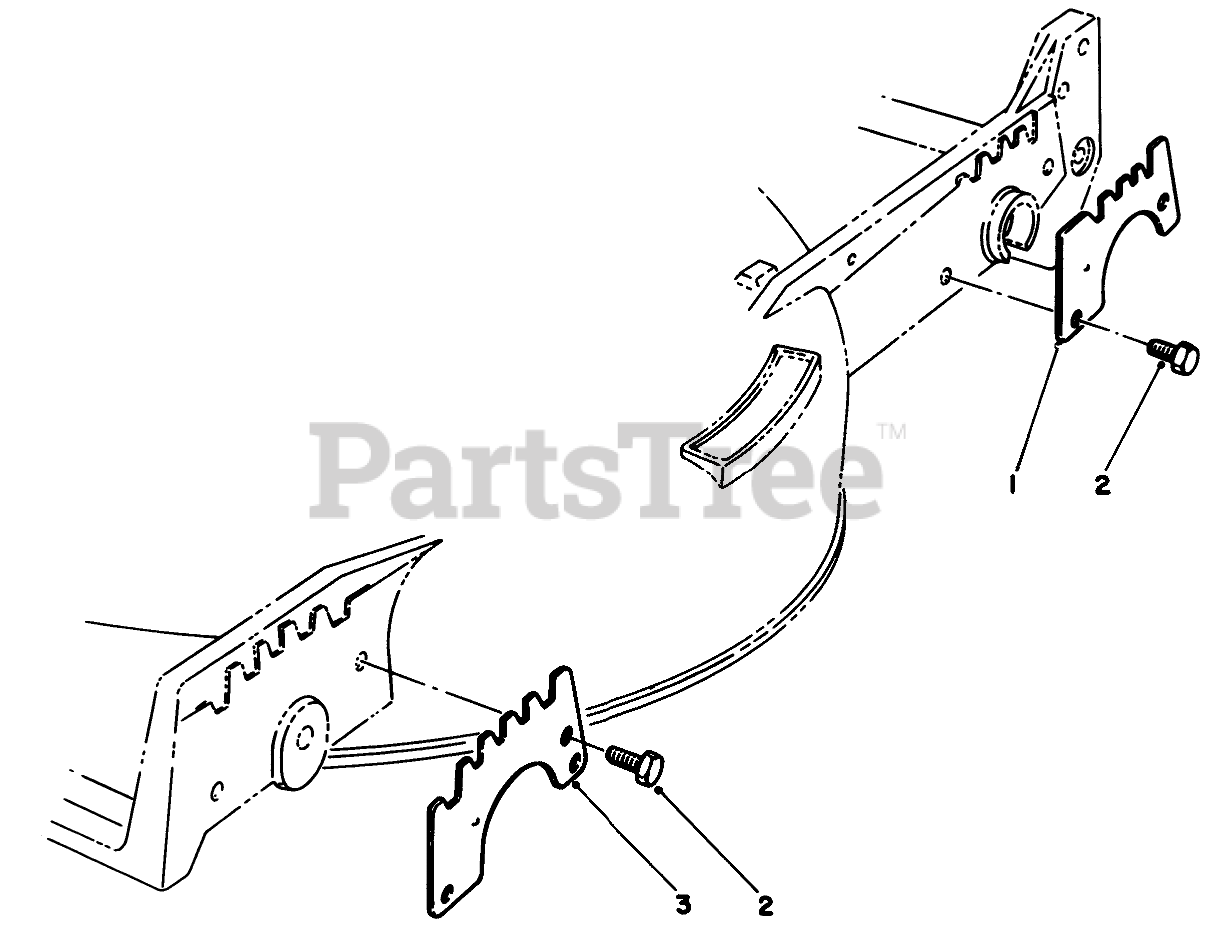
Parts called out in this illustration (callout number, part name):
1	WEAR PLATE,REAR
2	SCREW-HWH
3	WEAR PLATE
